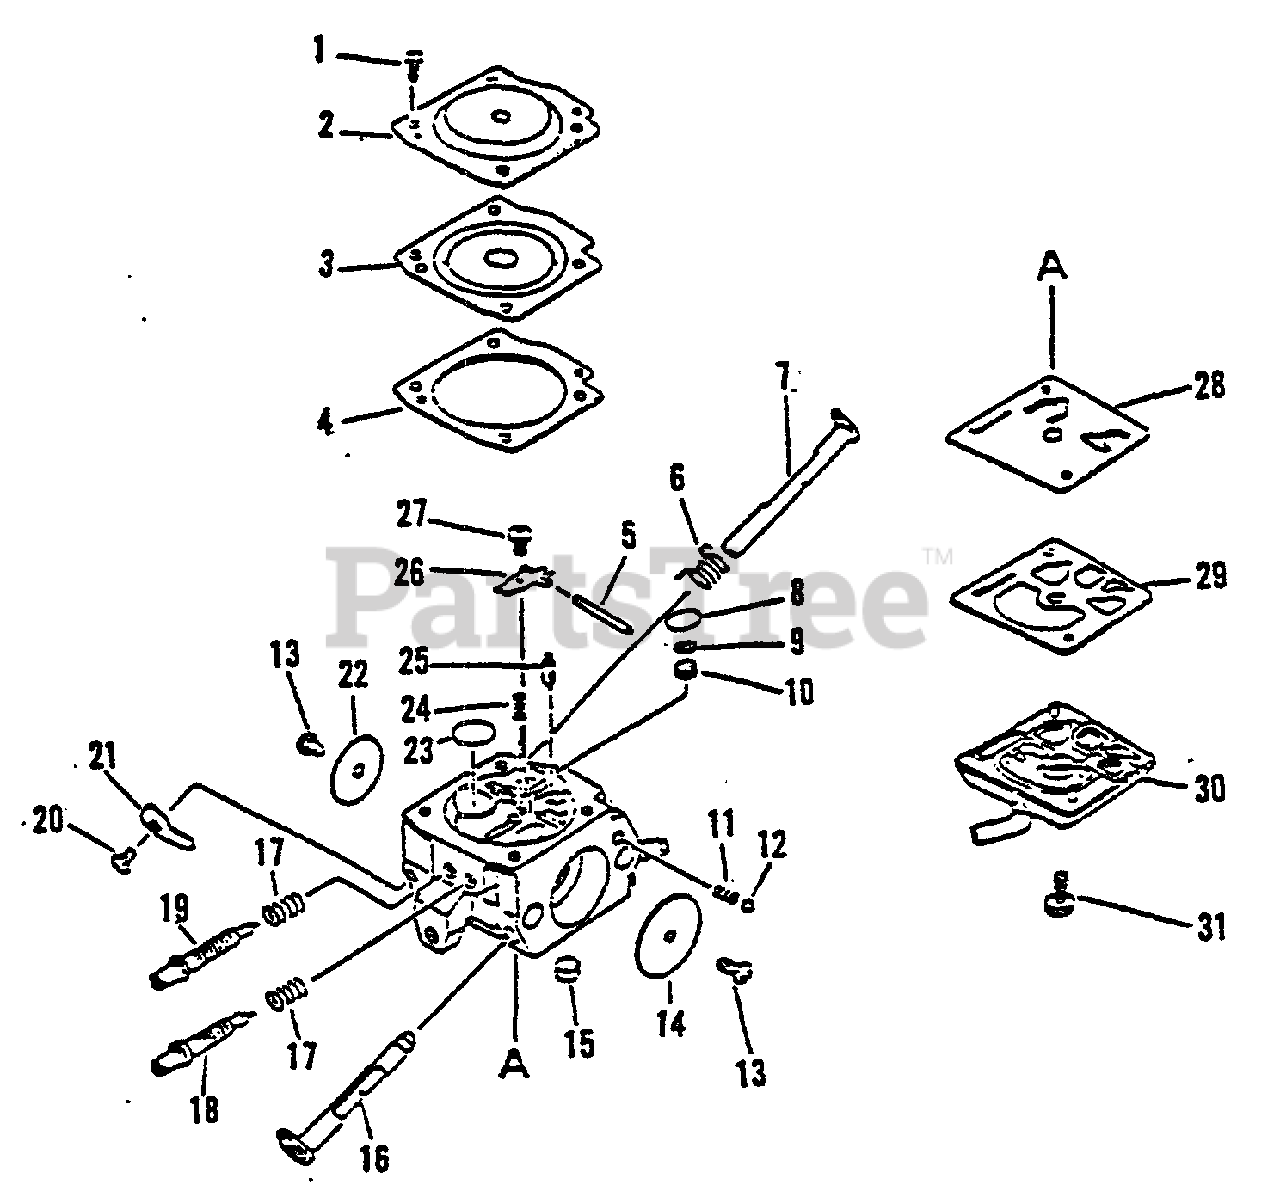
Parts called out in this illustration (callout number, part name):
1	SCREW
2	COVER, METERING
3	DIAPHRAGM
4	GASKET, DIAPHRAGM
5	PIN, METERING LEVER
6	SPRING, RETURN
7	SHAFT, THROTTLE
8	PLUG, WELCH
9	RING, RETAINING
10	STRAINER
11	SPRING
12	BALL, CHOKE
14	VALVE, CHOKE
15	STRAINER
16	SHAFT, CHOKE
17	SPRING
18	NEEDLE - HIGH SPEED
19	NEEDLE - LOW SPEED
21	LEVER, THROTTLE
22	VALVE, THROTTLE
23	PLUG, WELCH
24	SPRING
25	VALVE, NEEDLE
26	LEVER, METERING
27	SCREW
28	DIAPHRAGM, PUMP
29	GASKET, PUMP
30	BASE, PURGE
31	SCREW, PUMP COVER
